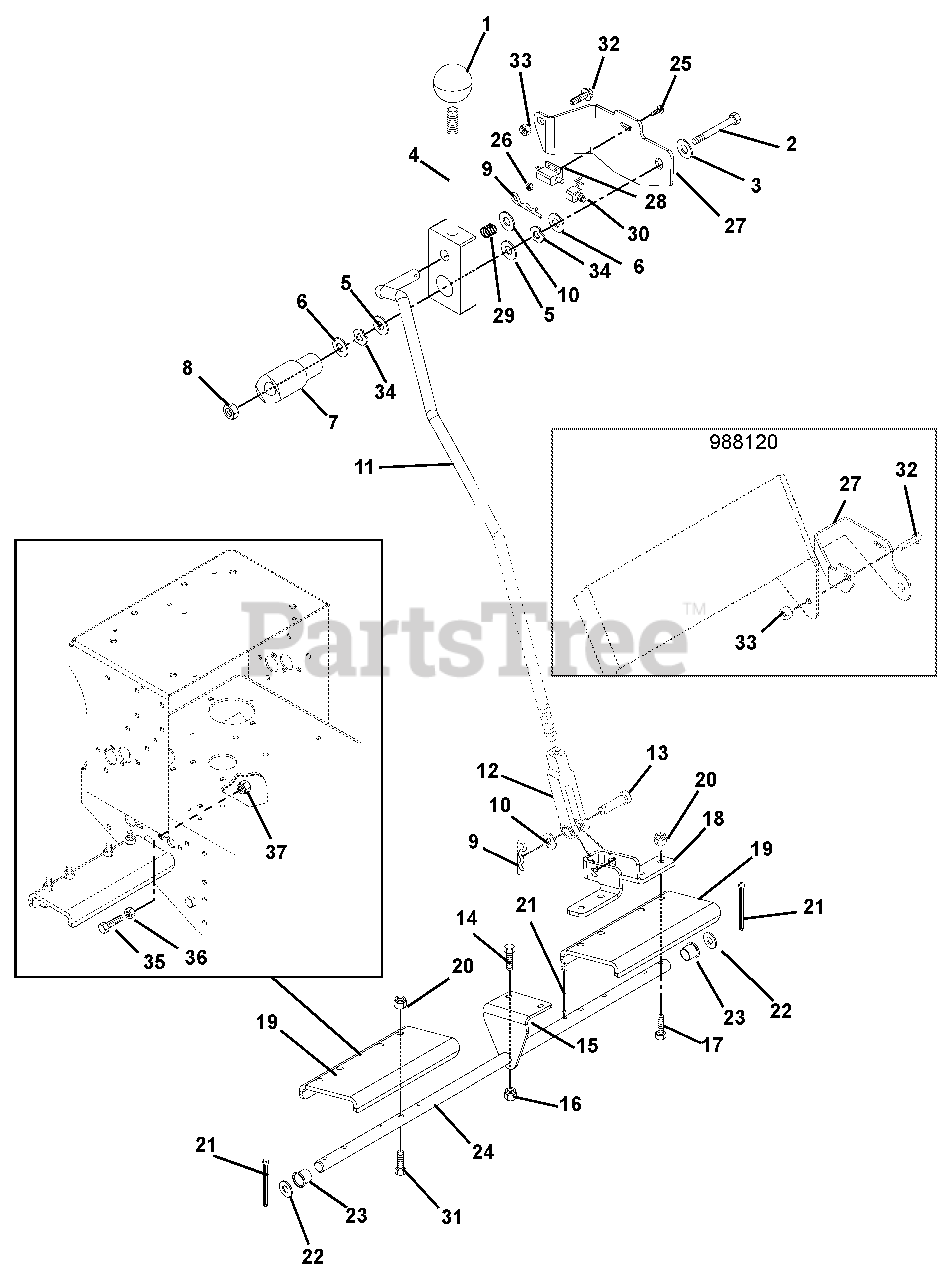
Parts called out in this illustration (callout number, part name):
1	Knob, Ball-Black 1-.41, .375-1
2	Bolt-Hex .44-14 x 4.5 Grade 5
3	Washer-Flat-Steel .50 x 1.25 x .083
4	Weldment- Handle
5	Washer-Flat-Nylon .76 x 1.25 x .030
6	Washer-Flat-Steel .76 x 1.38 x .062
7	Pivot, Brake
8	Nut-Locking-Hex .44-14
9	Pin-Hair Internal .08 x .18 x 1.18
10	Washer-Flat-Steel .406 x .812 x .065
11	Rod, Brake (105, 106, 108, 109)
12	Clevis,.38-24 Adjustable
13	Pin-Clevis .37 x 1.75
14	Bolt-Hex .38-16 x 1.00 Grade 5
15	Bracket, Brake Shaft
16	Nut-Locking-Nylon .38-16
17	Bolt-Hex .25-20 x 1.50 Grade 5
18	Brake, Arm
19	Pad, Brake
20	Nut-Locking-Nylon .25-20
21	Pin-Cotter .12 x 1.00
22	Washer-Flat-Steel .656 x 1.31 x .095
23	Bushing-Flange .63 x 1.00 x .625 Nylon
24	Brake, Shaft
25	Screw-Machine 10-24 x .75 Hex Washer Head
26	Nut-Locking-Nylon 10-24 with Insert
27	Bracket, Parking Brake Switch (105, 106, 108, 109)
28	Switch, Interlock
29	Spring-Compression .045 x .60 x .75
30	Boot, Rubber
31	Bolt-Hex .25-20 x 1.25 Grade 5
32	Bolt-Serrated Hex Flange Washer Head .25-20 x .75 (105, 106, 108, 109)
33	Nut-Locking-Top-Flange .25-20 (105, 106, 108, 109)
34	Washer-Wave .076 x 1.12 x .080
35	Bolt-Hex .38-16 x 1.75 Grade 5
36	Nut-Hex .38-16
37	Nut-Locking-Nylon .38-16
